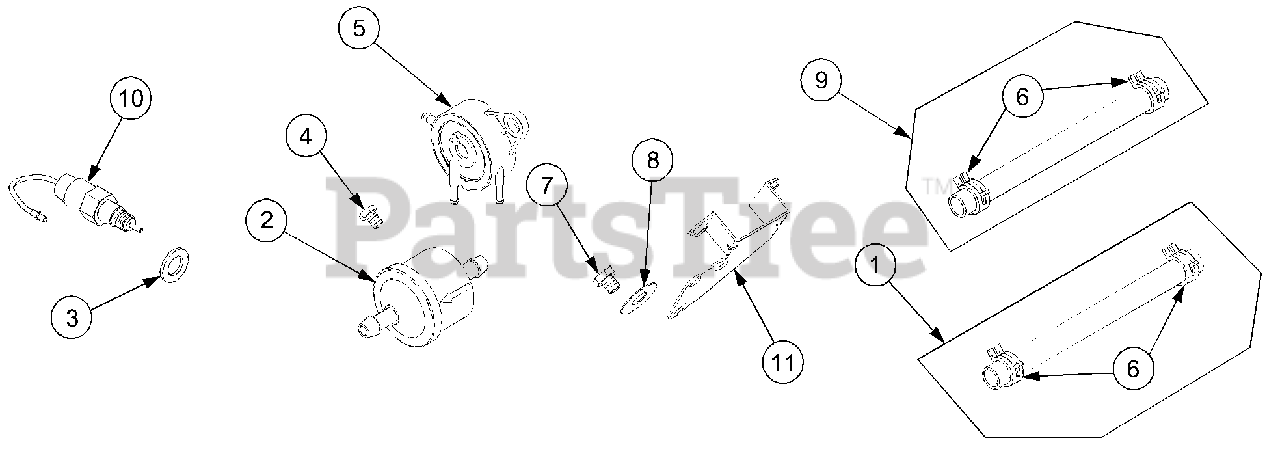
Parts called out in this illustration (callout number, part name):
1	Line, Fuel
2	Filter, Fuel
3	Washer, Sealing
4	Screw, Fuel Pump
5	Pump, Fuel
6	Clamp, Hose
7	Screw, Fuel Pump Bracket
8	Bracket, Fuel Pump
9	Hose, Vacuum
10	Solenoid, Fuel
